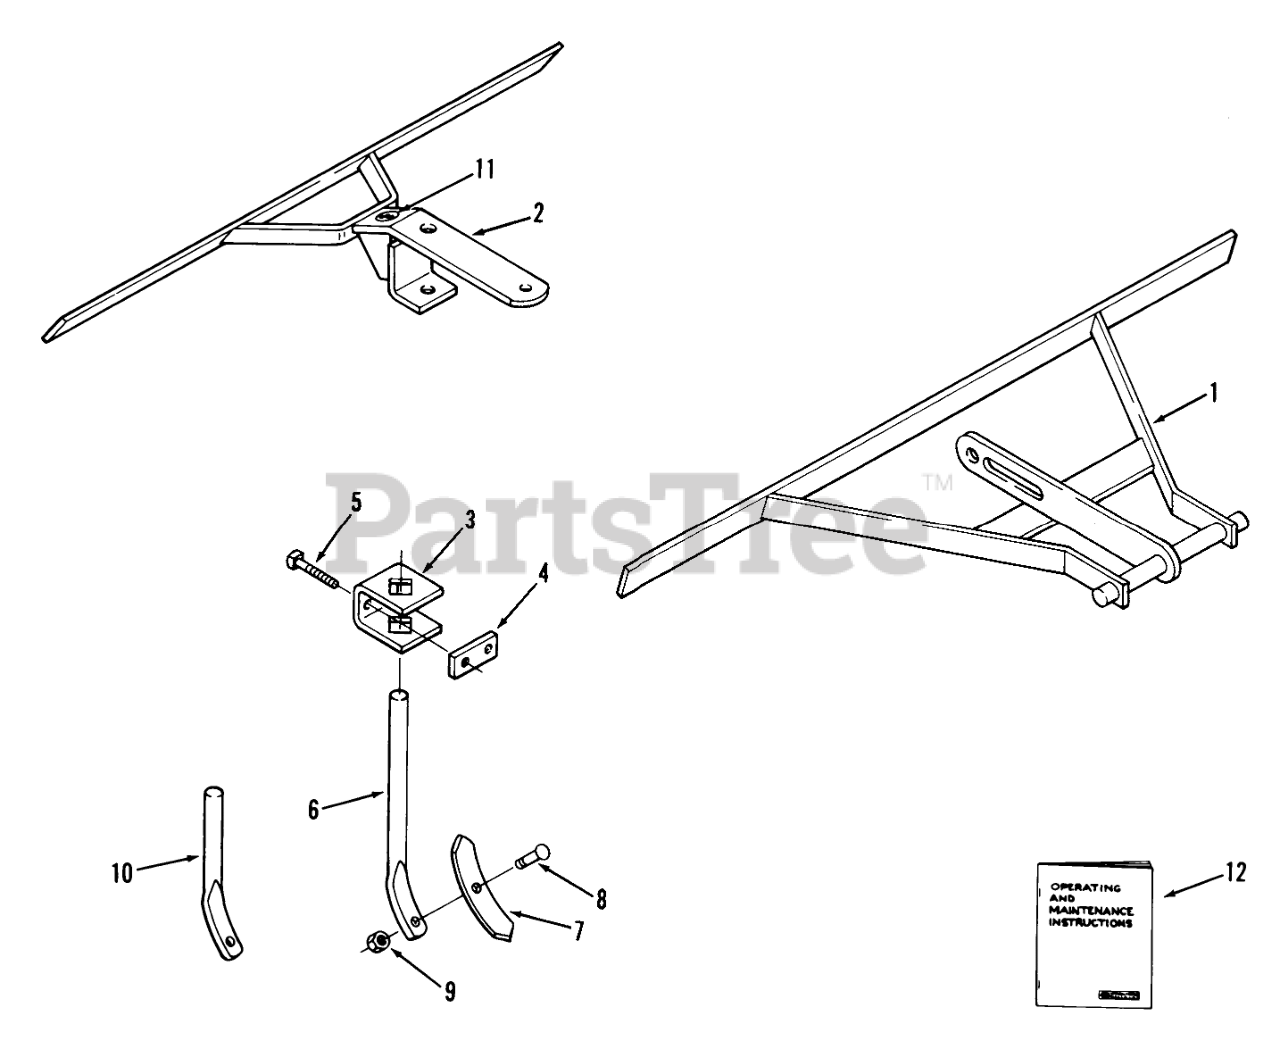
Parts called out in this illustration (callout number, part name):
1	Frame Assembly-Front
2	Frame Assembly-Rear
3	Clamp
4	PLATE
5	SQ HD CUP POINT SCR
6	Standard
7	Shovel
8	PLOW BOLT
9	Nut
10	STANDARD SHOVEL
11	DECAL-WHEEL HORSE
12	Operating and Maintenance Instructions
